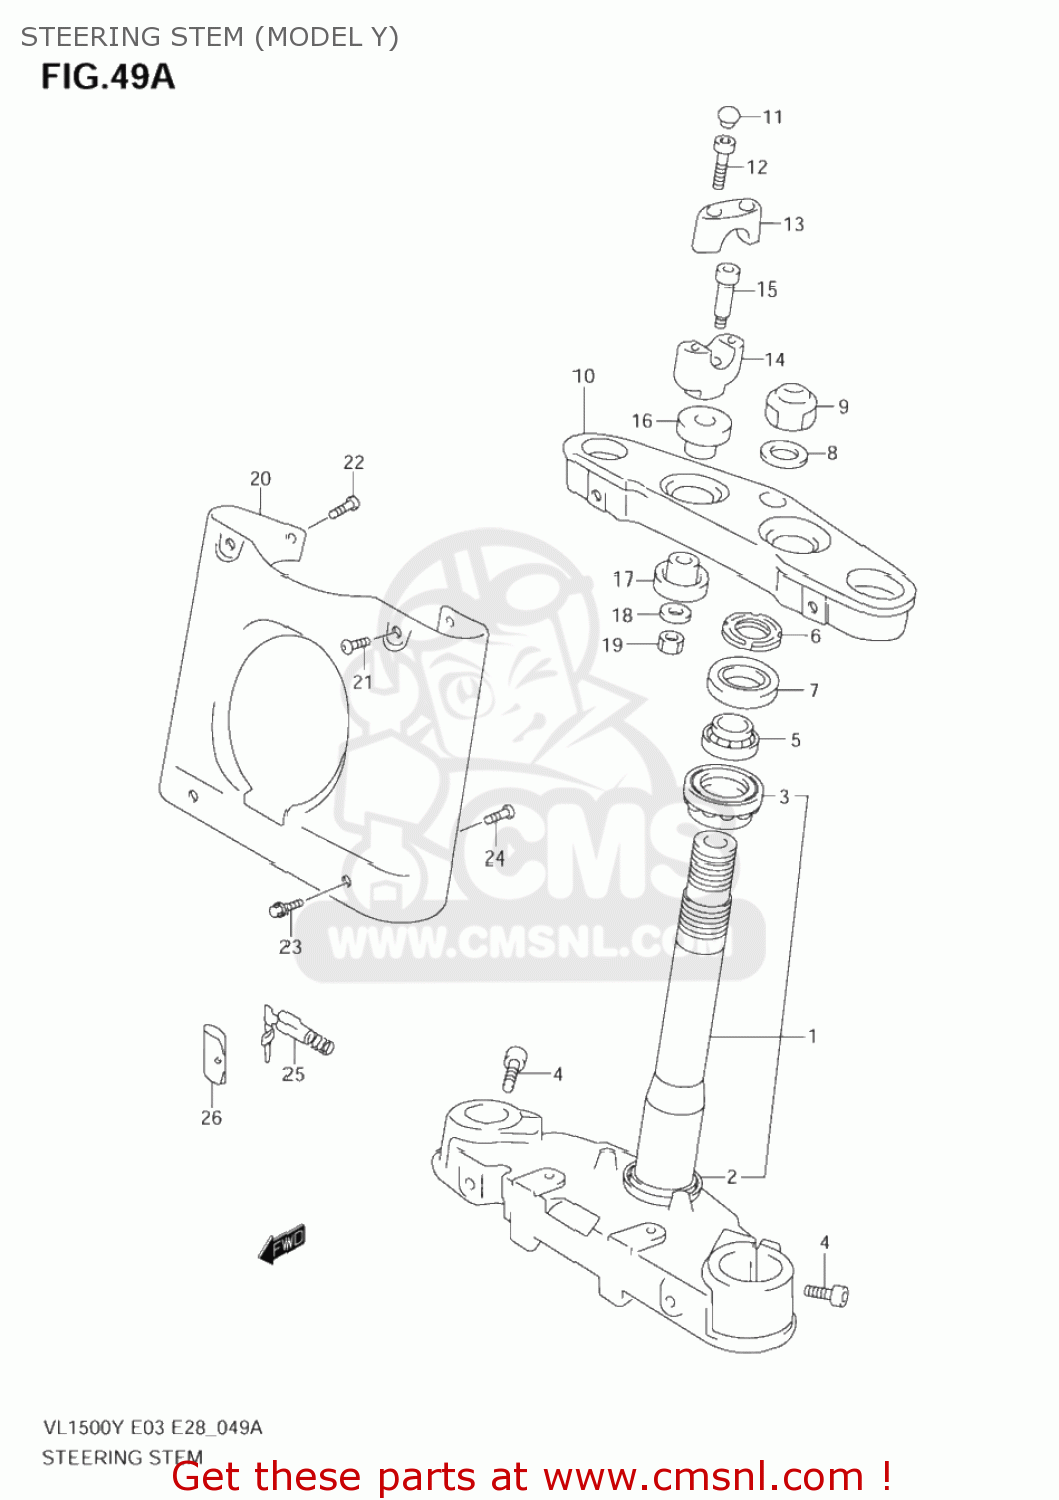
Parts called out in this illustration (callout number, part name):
1	BRACKET,FR FORK UNDER
2	SEAL,STEERING LWR
3	BEARING(30X55X17)
4	BOLT,STEM
5	BEARING(25X47X15)
6	NUT,STEERING STEM(25X44X10)
7	DUST SEAL,STEERING UPR
8	WASHER(22.5X32X1.6)
9	NUT,CAP
10	HEAD,STEERING STEM
11	CAP(OD:14.5)
12	BOLT
13	HOLDER,HANDLE UPR
14	HOLDER,HANDLE UNDER
15	BOLT
16	DAMPER,RUBBER
17	CUSHION,RUBBER UNDER
18	WASHER
19	NUT
20	COVER,FR FORK UPR
21	SCREW(8X16)
22	SCREW(6X12)
23	BOLT
24	SCREW(6X12)
25	LOCK SET,STEERING
26	CASE,STEERING KEY
